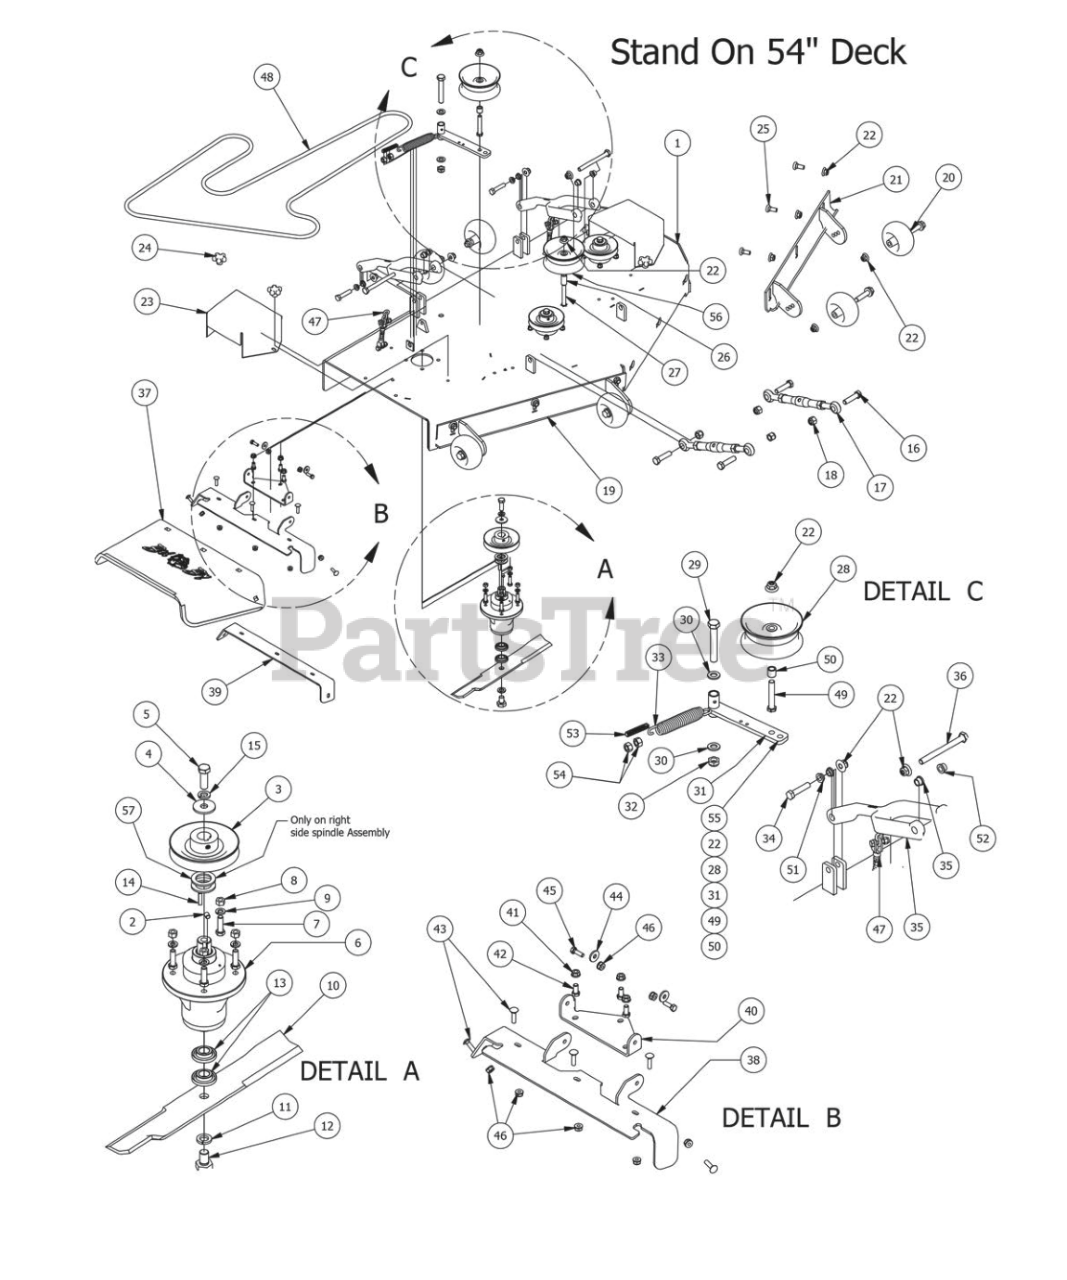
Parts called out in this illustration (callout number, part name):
1	54" Stand Up Deck
2	5/16 Set Screw
3	5" Deck Pulley
4	1/2 Belleville Washer
5	1/2"-20 x 1 1/2 - Grade 5 Fine Thread Bolt
6	Double Bearing Spindle
7	3/8" x 1 1/4" Hex Bolt
8	3/8-16 Hex Nuts Zinc
9	3/8" Lock Washer
10	54" Deck Fusion Blade For Outlaw
11	5/8" Lock Washer
12	5/8" x 1 1/2" Grade 8 Bolt
13	Double Bearing For Spindle
14	1/4" x 1" Key
15	1/2" Lock Washer
16	5/8" x 2 1/2" Hex Bolt
17	Turnbuckle (Top Link)
18	5/8 Std NC Nylock Nut
19	54 Outlaw Adjustable Deck Front (left)
20	Deck Wheel
21	54 Outlaw Adjustable Deck Front (Right)
22	1/2-13 Nylon Flange Nut-Orange
23	Pulley Cover
24	5/16" Knob
25	1/2" x 1 1/4 Carriage Bolt
26	.502 ID X.75 OD X 1.500 Leng
27	1/2 x 3 1/2 Flange Bolt Grade 8
28	5 3/4" Deck Idler Pulley
29	5/8" x 4" Hex Bolt
30	.635 ID Plastic Washer
31	Deck Idler 2009 AOS
32	5/8" Nylock (1/2 Jam)
33	2009 Deck/Pump Idler Spring
34	1/2-13X 2-1/4 GR Hex Bolts
35	Deck Arm Assembly
36	1/2" x 5 1/2" Bolt
37	Rubber Discharge Chute
38	60" Discharge Chute Upper Hanger
39	60" Lower Hanger
40	Discharge Chute Hanger
41	3/8" Flange Nut
42	3/8" x 3/4" Hex Bolt
43	5/16" x 1 1/4" Carriage Bolt
44	.360 ID Plastic Washer
45	5/16" x 1" Bolt
46	5/16-18 Nylon Flange Nut
47	4-Link Adjustable Deck Hange
48	42" Deck Belt-B120
49	1/2-13 x GR 5 Hex Bolt Zinc
50	3/4 OD x 1/2 ID x 3\4 Length
51	Flange for Lower Deck Arm
52	Flange Bushing for Deck Arm Upper
53	All Thread-pump Idler Tensioner
54	1/2" Hex Nut
55	Deck Idler Assembly Components 22,28,31,49,50
56	5 3/4" Deck Idler Pulley
57	1 1/8" Flat Spacer
